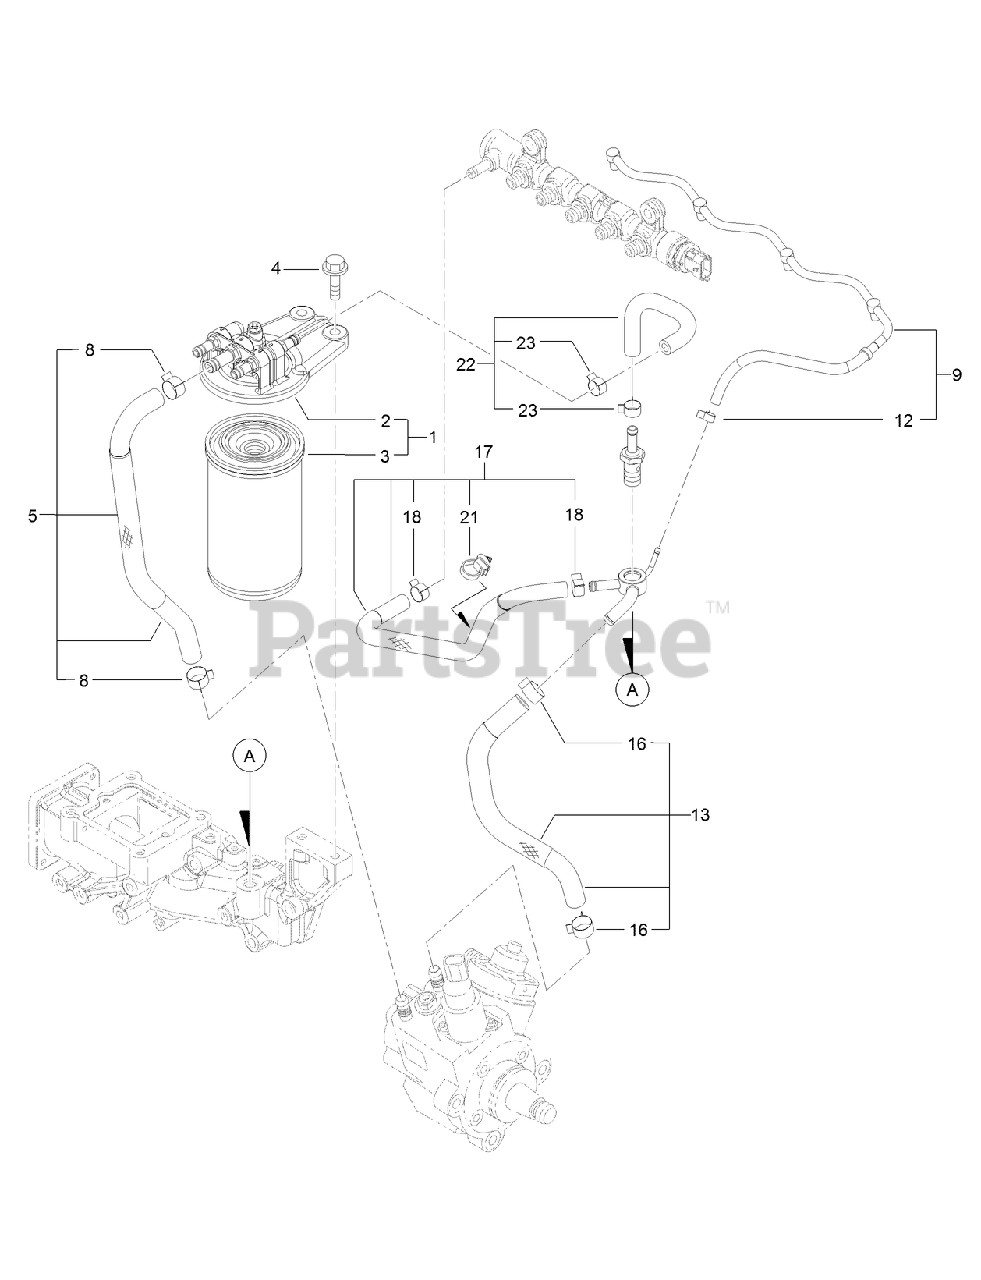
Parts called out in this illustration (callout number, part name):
1	FUEL/OIL FILTER ASM
2	FUEL/OIL FILTER BRACKET ASM
3	FILTER-FUEL/OIL
5	FUEL HOSE ASM
8	CLAMP-HOSE
9	FUEL RETURN PIPE ASM
12	CLAMP-HOSE
13	FUEL/OIL RETURN HOSE ASM
16	CLAMP-HOSE
17	FUEL/OIL RETURN HOSE ASM
18	CLIP-HOSE
21	BAND-CLIP
22	FUEL RETURN HOSE ASM
23	CLIP-HOSE
